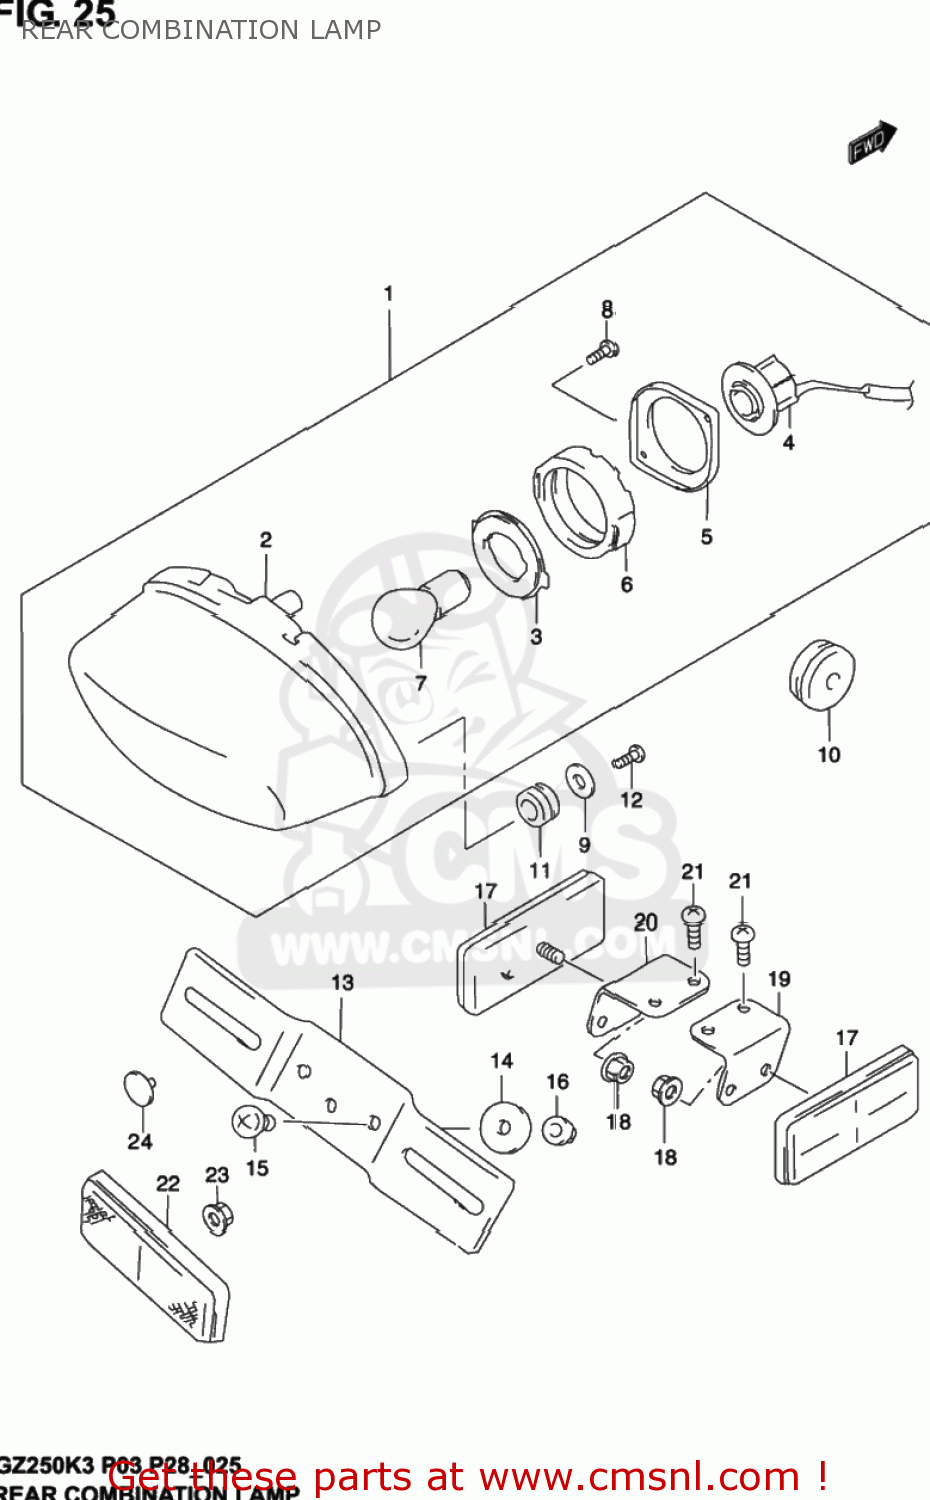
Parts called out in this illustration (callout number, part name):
1	LAMP ASSY,RR COMBINATION
2	LAMP UNIT
3	PLATE NO.1
4	SOCKET & CORD
5	PLATE NO.2
6	CUSHION
7	BULB(12V21/5W)
8	SCREW
9	WASHER(5.5X20X1.2)
10	GROMMET
11	CUSHION
12	SCREW
13	BRACKET,LICENSE PLATE
14	WASHER(6.5X20X1.6)
15	SCREW 6X12
16	NUT
17	REFLECTOR REAR
18	NUT
19	BRACKET,RR SIDE RR,L
20	BRACKET,RR SIDE RR,R
21	SCREW
22	REFLECTOR REAR
23	NUT
24	CUSHION
